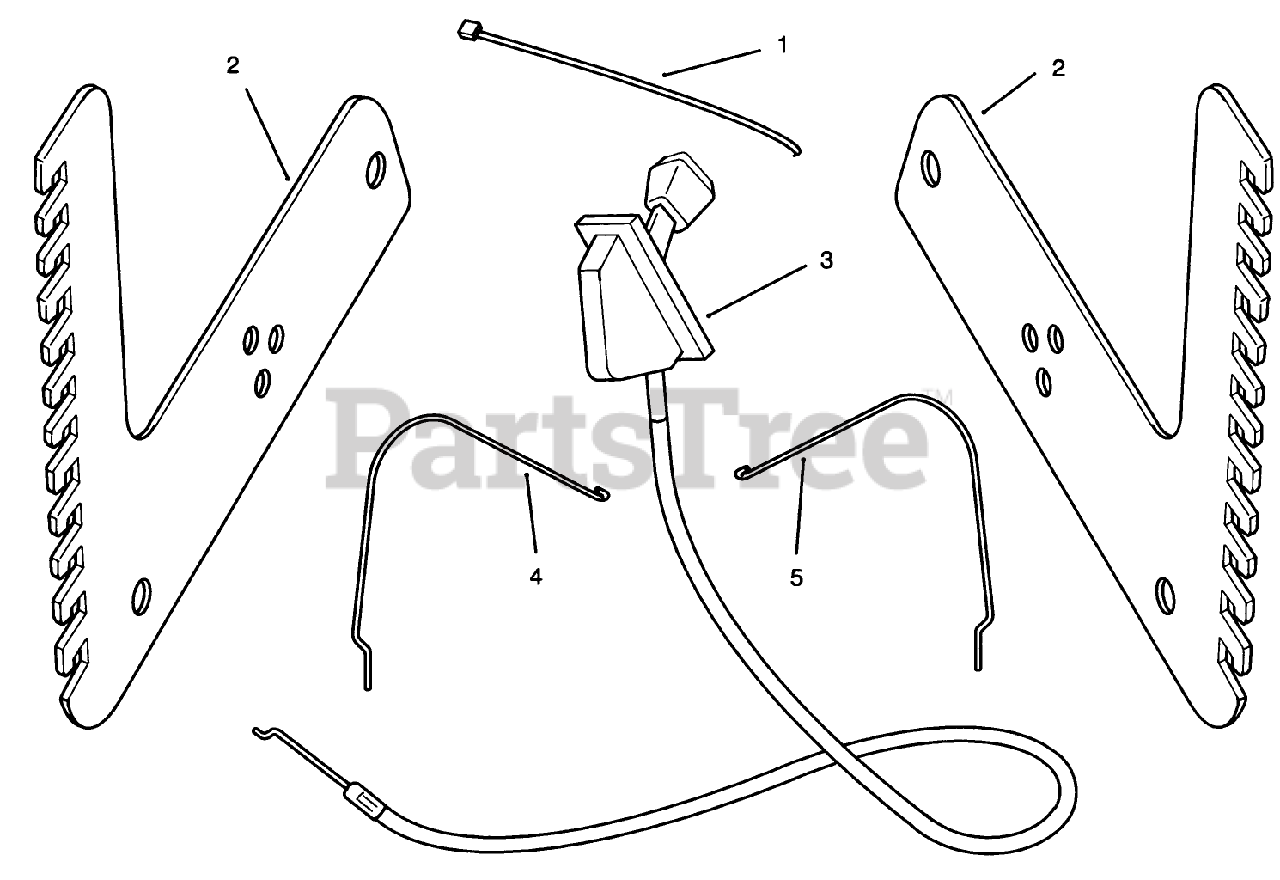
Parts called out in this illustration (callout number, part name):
1	TIE-CABLE
2	BRACKET - ADAPTOR
3	CONTROL - GROUND SPEED
4	SPRING - HOLD DOWN LH
5	SPRING - HOLD DOWN RH
